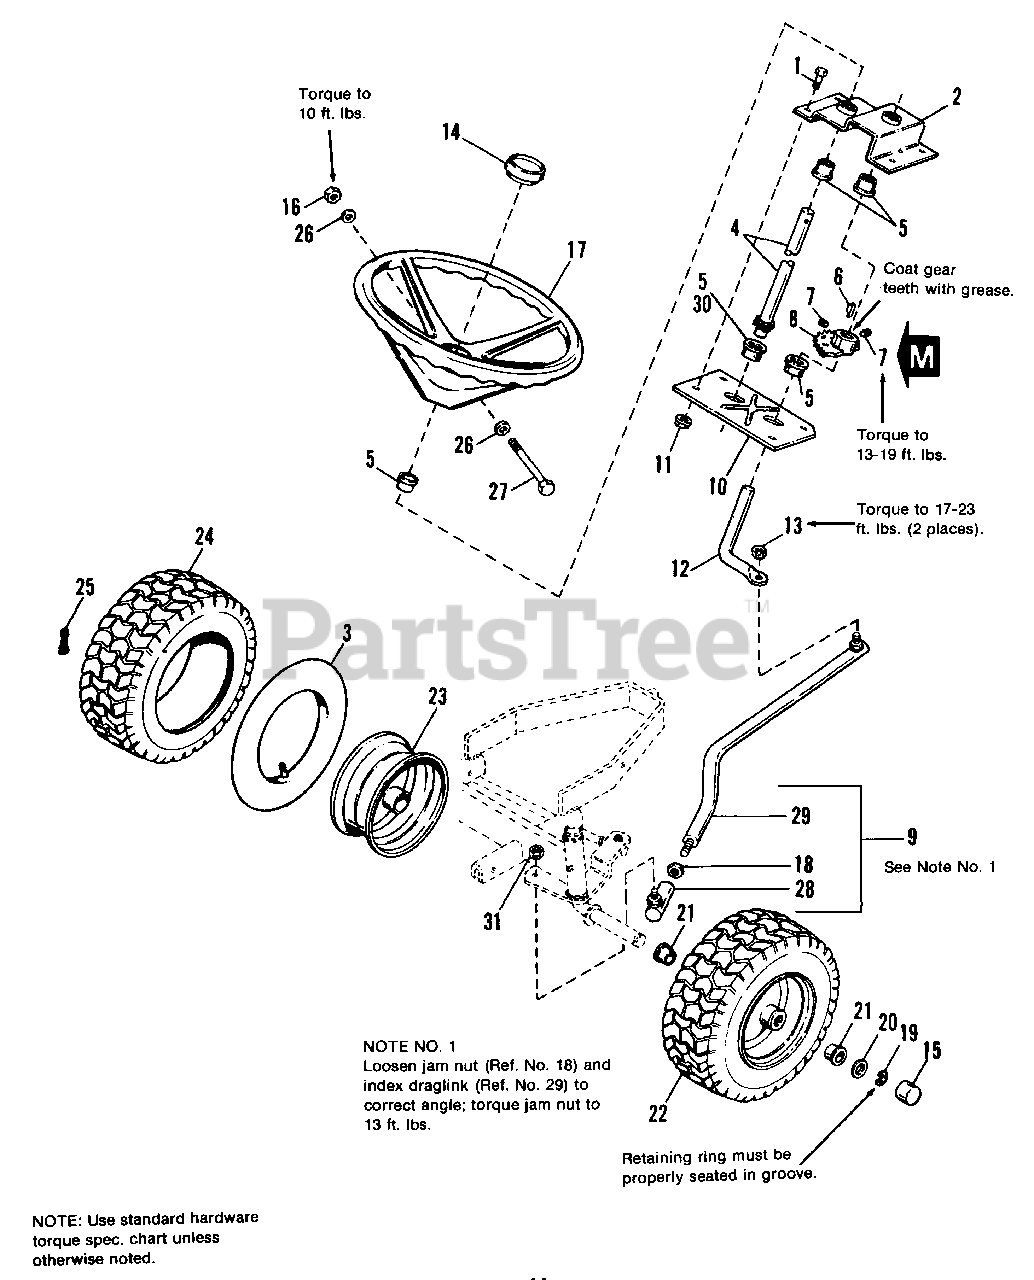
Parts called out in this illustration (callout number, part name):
1	CAPSCREW, 5/16-18 x 3/4
2	TOP PLATE, Steering
3	TUBE (For Service Only)
4	SHAFT ASSY., Steering
5	BUSHING (Qty. 4 on 1691427, 1691541)
7	SETSCREW, 5/16-18 x 1/2
8	GEAR, Steering
9	LINK ASSY., Drag (Incl. Ref. Nos. 18, 28 & 29)
10	BASE PLATE, Steering
11	LOCKNUT, Flange, Whiz, 5/16-18
12	ROD, Steering
13	LOCKNUT, Center, 3/8-24
14	CAP, Steering Wheel
15	CAP, Hub, Threaded
16	LOCKNUT, Hex, 5/16-18
17	WHEEL, steering
18	NUT, Jam, 3/8-24
19	KLIPRING, Ext., 3/4
21	BEARING, 1.13 O.D.
21	BEARING, 1.38 O.D.
22	WHEEL & TIRE ASSY., 13 x 5.00-6 (Turf-Mate)
22	WHEEL & TIRE ASSY., 13 x 6.00-6 (Turf Saver)
22	WHEEL & TIRE ASSY., 15 x 6.00-6 (Turf Mate)
22	WHEEL & TIRE ASSY., 15 x 6.00-6 (Turf-Saver)
23	WHEEL, w/Bearings, 13 x 5.00
23	WHEEL, w/Bearings, 15 x 6.00
24	TIRE (Carlisle) 15 x 6.00-6(12 HP) Turf-Saver
24	TIRE (Carlisle) 15 x 6.00-6(12 HP) Turf Mate
24	TIRE (Carlisle) 13 x 5.00-6(10 HP) Turf-Saver
24	TIRE (Carlisle) 13 x 5.00-6(10 HP) Turf Mate
25	STEM, Valve
26	WASHER, Plain, 5/16
27	BOLT, Hex, 5/16-18 x 3-1/2
28	BALL JOINT ASSY., 3/8-24 Thrd. Stud.
28	BALL JOINT ASSY., 1/2-20 Thrd. Stud.
30	BUSHING (Mfg. No. 1691427, 1691541 only)
31	LOCKNUT, Center, 3/8-24 (Early Models)
31	LOCKNUT, Center, 1/2-20 (Later Models)
